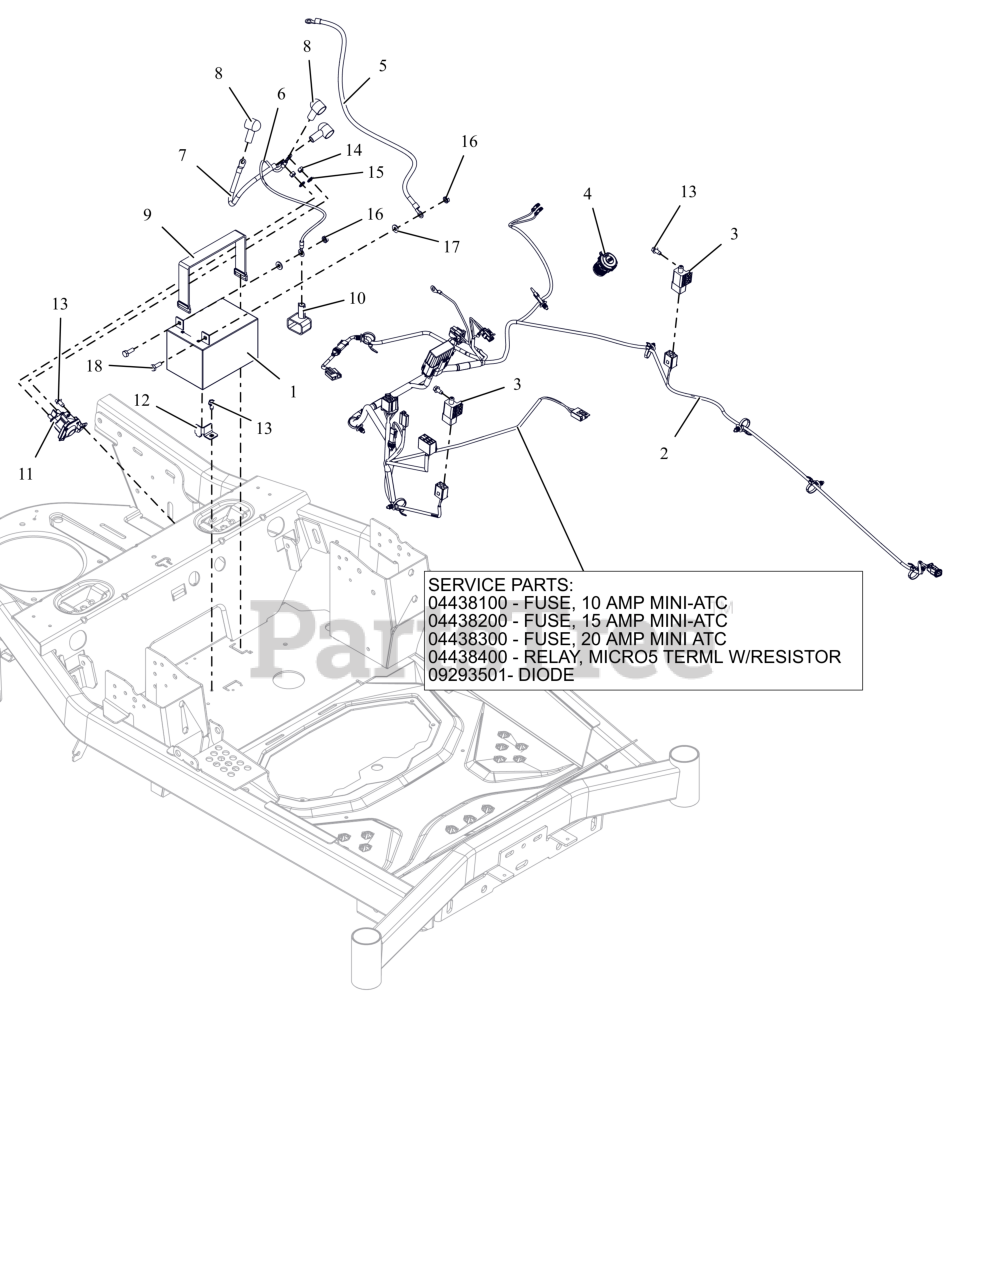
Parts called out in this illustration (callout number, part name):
1	BATTERY, 12V 12A -190CCA
2	HARNESS, MAIN IKON 23
2	FUSE,10 AMP MINI-ATC
2	FUSE,15 AMP MINI-ATC
2	FUSE,20 AMP MINI ATC
2	RELAY,MICRO5 TERML W/RESISTOR
2	DIODE, CONNECTOR SHELL
3	SWITCH-BRAKE NO/NO-POST & HOLE
4	USB, DUAL PORT USB-C, 12V BLK
5	CABLE-NEGATIVE BATTERY 24.00"
6	CABLE,POS W/2 1/4 RING 18.5 LG
7	CABLE, POS W/(2)1/4 RING 9.0LG
8	BOOT, EYELET TERMINAL
9	STRAP- RUBBER
10	INSULATOR
11	SOLENOID, STARTER (SEALED)
12	RETAINER, BATTERY CORNER (BLACK)
13	SCR-TAP .25-20X.50 HWH ZCC
14	NUT-STD M6-1.0 ZCC
15	WSHR,LK-EXT.262X.502X.026 ZCC
16	NUT-KEPS .250-20 ZCC
17	WSHR,FLT .281X.625X.065 ZCC
18	BLT, HEX .25-20X.75 G5 ZCC
